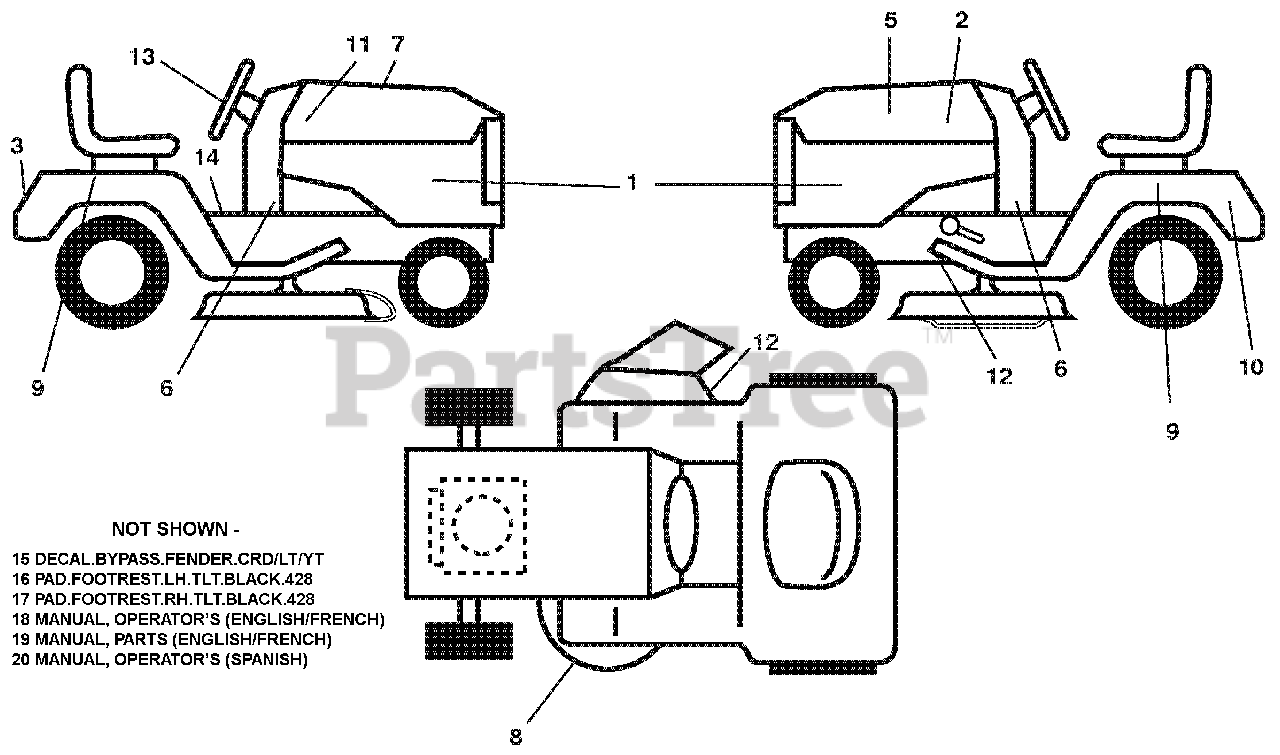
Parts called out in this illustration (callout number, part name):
1	DECAL.SDPNL.PWRDBY KOHL.ARIENS
2	DECAL, HOOD RH
3	DECAL.FENDER.REAR.ARIENS
4	DECAL.FENDER.WARNING.ENG/FR.07
5	DECAL.RPL.KH.SNGL.TLW.42.T2
6	DECAL.DASH.LOWER.19HP.ARIENS
7	DECAL, ETHANOL
8	DECAL.V-BELT.SCH.42/46"MEC/ELE
9	DECAL.FENDER.SIDE.HYDRO.ARIENS
10	DECAL.BAT.DAN/POI P/L SYM.WPN
11	DECAL, HOOD LH
12	DECAL.MOWER.WARN.KEEP HAND AWY
13	DECAL.WHEEL.STEER.ARIENS
14	Decal, Flag
15	DECAL.BYPASS.FENDER.CRD/LT/YT
16	PAD.FOOTREST.LH.TLT.BLACK.428
17	PAD.FOOTREST.RH.TLT.BLACK.428
18	MANUAL, OPERATOR'S (ENG/FRA)
19	MANUAL, PARTS (ENGLISH/FRENCH)
20	MANUAL, OPERTAOR'S (SPANISH)
